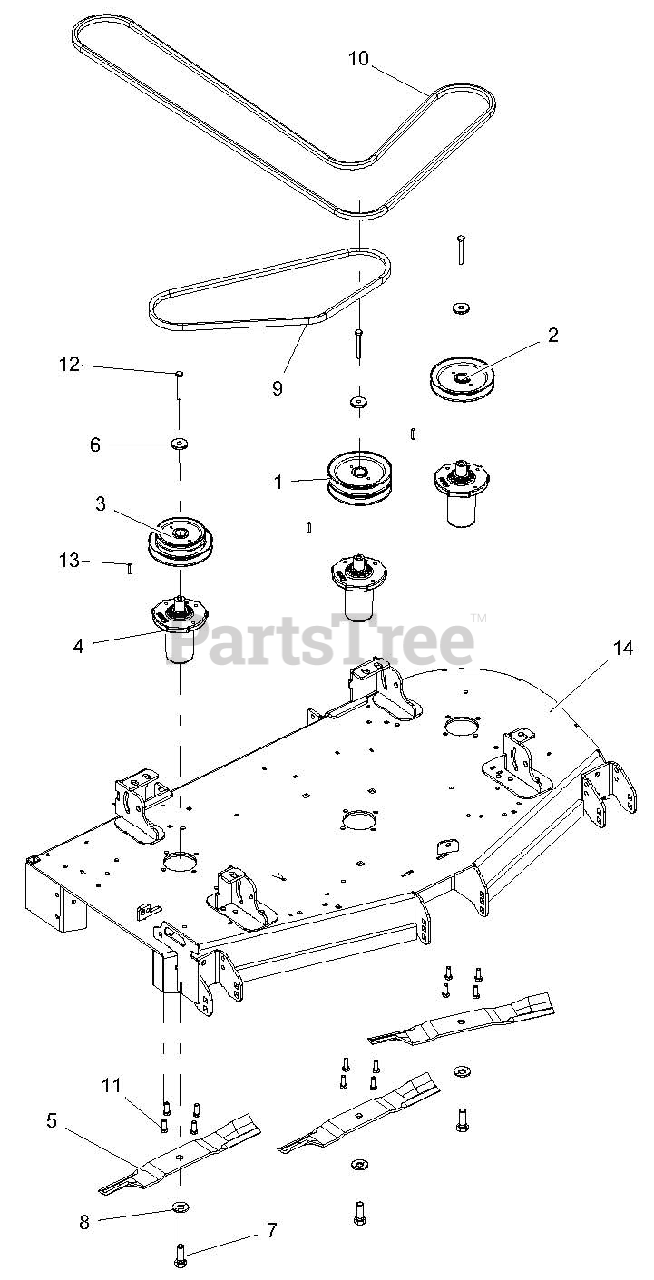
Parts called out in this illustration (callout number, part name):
1	PULLEY, DOUBLE -1" ID X 6.00" OD-BLACK
2	PULLEY, SINGLE -1" ID X 6.00" OD-BLACK
3	PULLEY, DOUBLE -1" ID X 6.00" & 4.75" OD
4	SERVICE, ASM SPINDLE- DUCTILE
5	BLADE, 18.00" MOVER
6	RETAINER, SHEAVE SPINDLE
7	BLT, HEX .62-18X1.75 GR8 YWZC
8	WSHR, BLVL .63X1.625X.14
9	BELT, B 56.00 RAW COGGED
10	BELT, BB 118.00 WRAPPED HEX
11	BLT-HEX .38-16X1.00 GR5 YWZC EP30
12	BLT-HEX .38-16X2.75 GR8 YWZC
13	KEY-SQ .250X.250X1.00 RC 40-50
14	WLDMT, 52" PT200 SIDE DISCHARGE DECK-RED
